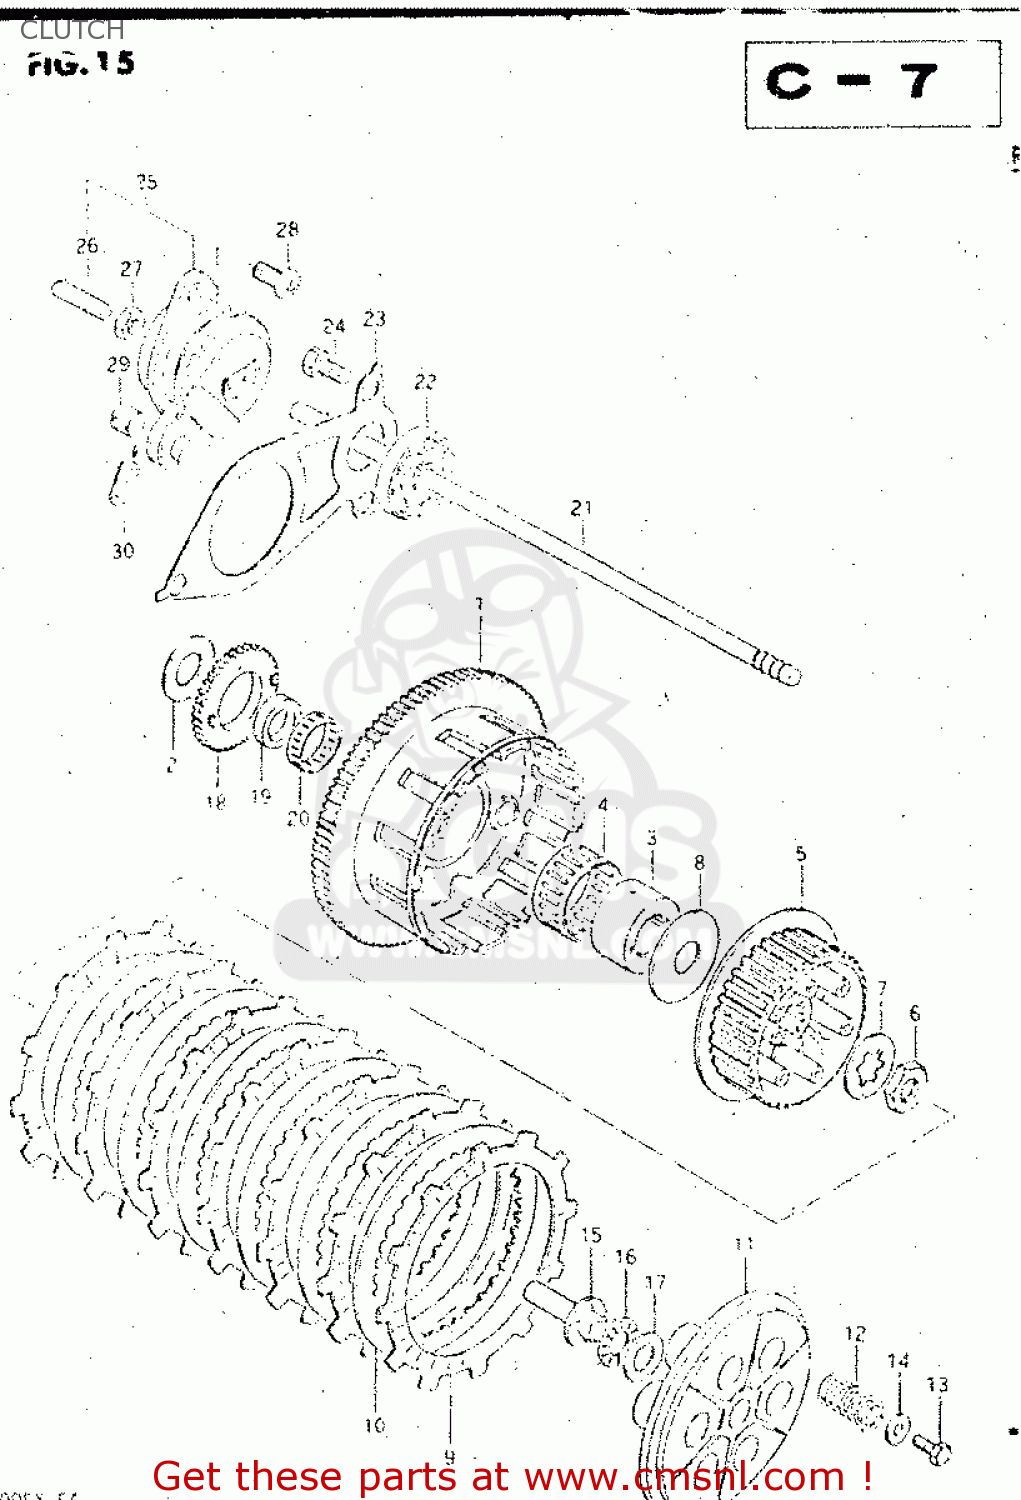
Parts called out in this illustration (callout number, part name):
1	GEAR ASSEMBLY,PRIMARY DRIVE NT:87
2	WASHER
3	SPACER,PRIMARY DRIVEN
4	BEARING
5	HUB,CLUTCH SLEEVE
6	NUT
7	WASHER,LOCK
8	WASHER(25X66X3.5)
9	PLATE,CLUTCH DRIVE (NAS)
10	PLATE,CLUTCH DRIVEN (NAS)
11	DISC,CLUTCH PRESSURE
12	SPRING
13	BOLT, UPPER
14	WASHER
15	PIECE,CLUTCH PUSH
16	BEARING(15X28X2)
17	WASHER
18	GEAR,ENG OIL PUMP DRIVE(NT:38)
19	SPACER,OIL PUMP DRIVE GEAR
20	BEARING(36X40X10)
21	ROD,CLUTCH PUSH
22	OIL SEAL
23	PLATE,CLUTCH PUSH ROD
24	BOLT
25	SCREW ASSEMBLY,CLUTCH RELEASE
26	SCREW
27	NUT 6MM
28	SCREW 6X12
29	PIECE,RELEASE ARM END
30	SPRING
